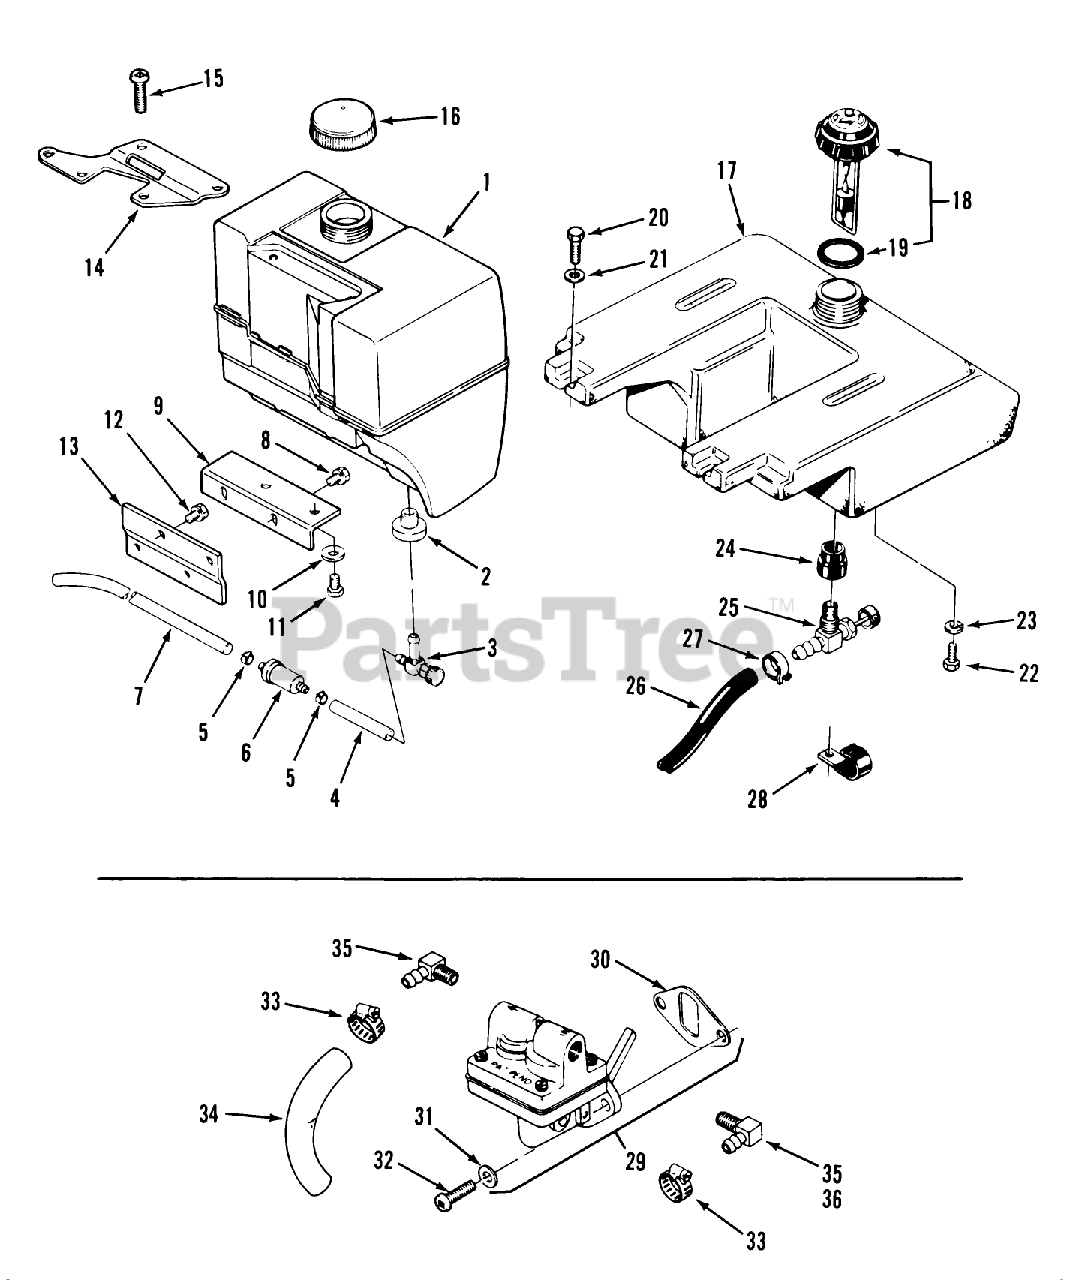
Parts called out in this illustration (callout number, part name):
2	KOHLER 41-158-03
3	KOHLER 25-462-01
4	KOHLER 41-353-10
5	KOHLER 25-237-01
7	KOHLER 41-353-12
8	KOHLER X-132-1
9	KOHLER 41-126-29
10	KOHLER X-25-53
11	KOHLER X-5-1
12	KOHLER 41-086-21
13	KOHLER 41-126-30
14	KOHLER 41-126-26
15	KOHLER 47-086-08
16	KOHLER 25-173-02
17	TANK-FUEL
18	ASSY-GAUGE CAP
25	VALVE-FUEL
29	KOHLER 41-559-04
30	KOHLER 25-041-05
31	KOHLER X-25-63
32	KOHLER X-174-2
33	KOHLER X-426-9
34	KOHLER 25-353-02
35	KOHLER 25-155-02
36	KOHLER X-391-11
